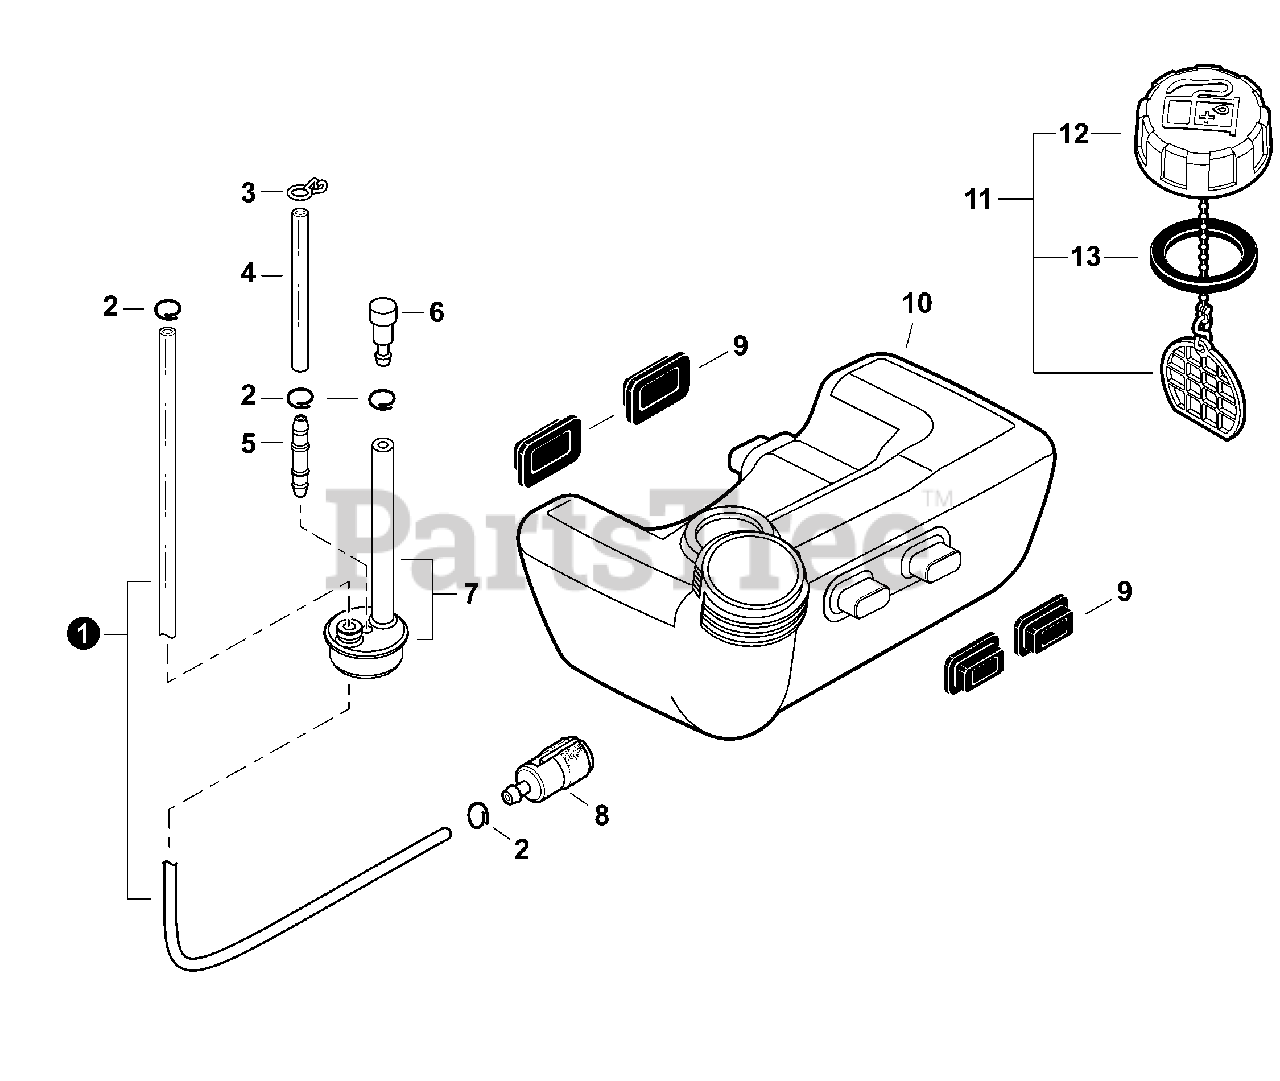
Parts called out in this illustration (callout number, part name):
1	PIPE, FUEL 3.3×6×160
2	CLIP Ø6
3	CLIP, SPRING Ø5.2
4	PIPE, FUEL RETURN
5	CONNECTOR, PIPE
6	VENT ASSY
7	GROMMET, FUEL W/VENT PIPE
8	FILTER, FUEL 125-528
9	CUSHION, FUEL TANK
10	TANK, FUEL
11	CAP ASSY, FUEL
12	CAP, FUEL
13	GASKET, FUEL CAP
